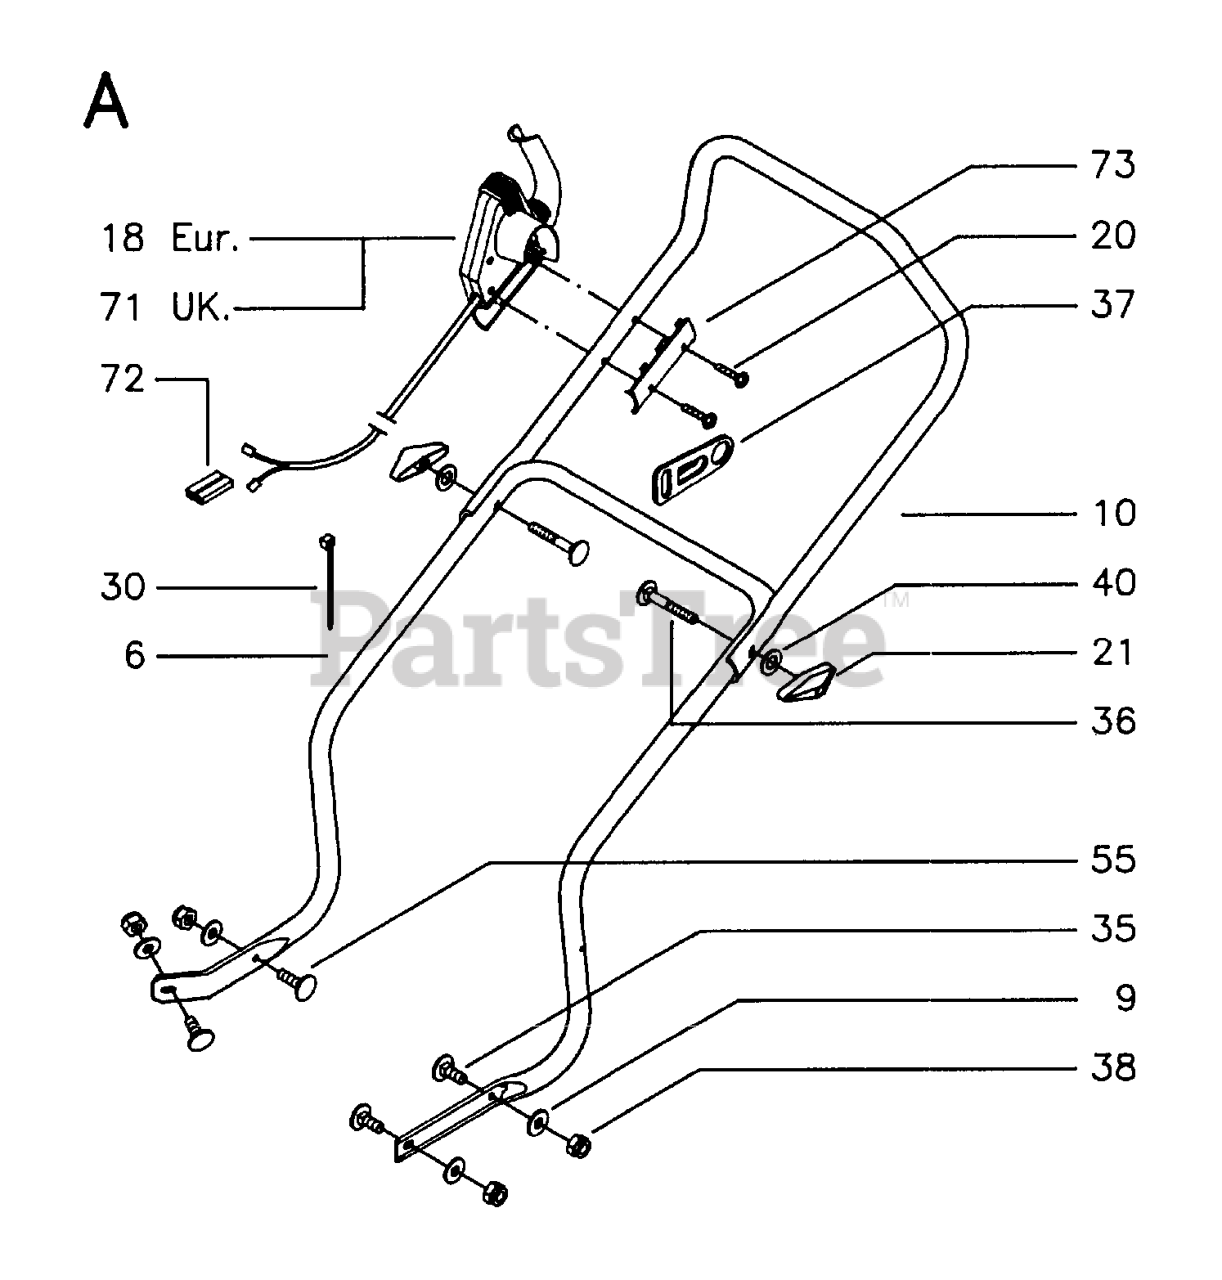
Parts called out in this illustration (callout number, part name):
21	WINGNUT
38	LOCKNUT M6
40	WASHER - 15X7.3X1.6
55	REPL BY 515 71 16-20
